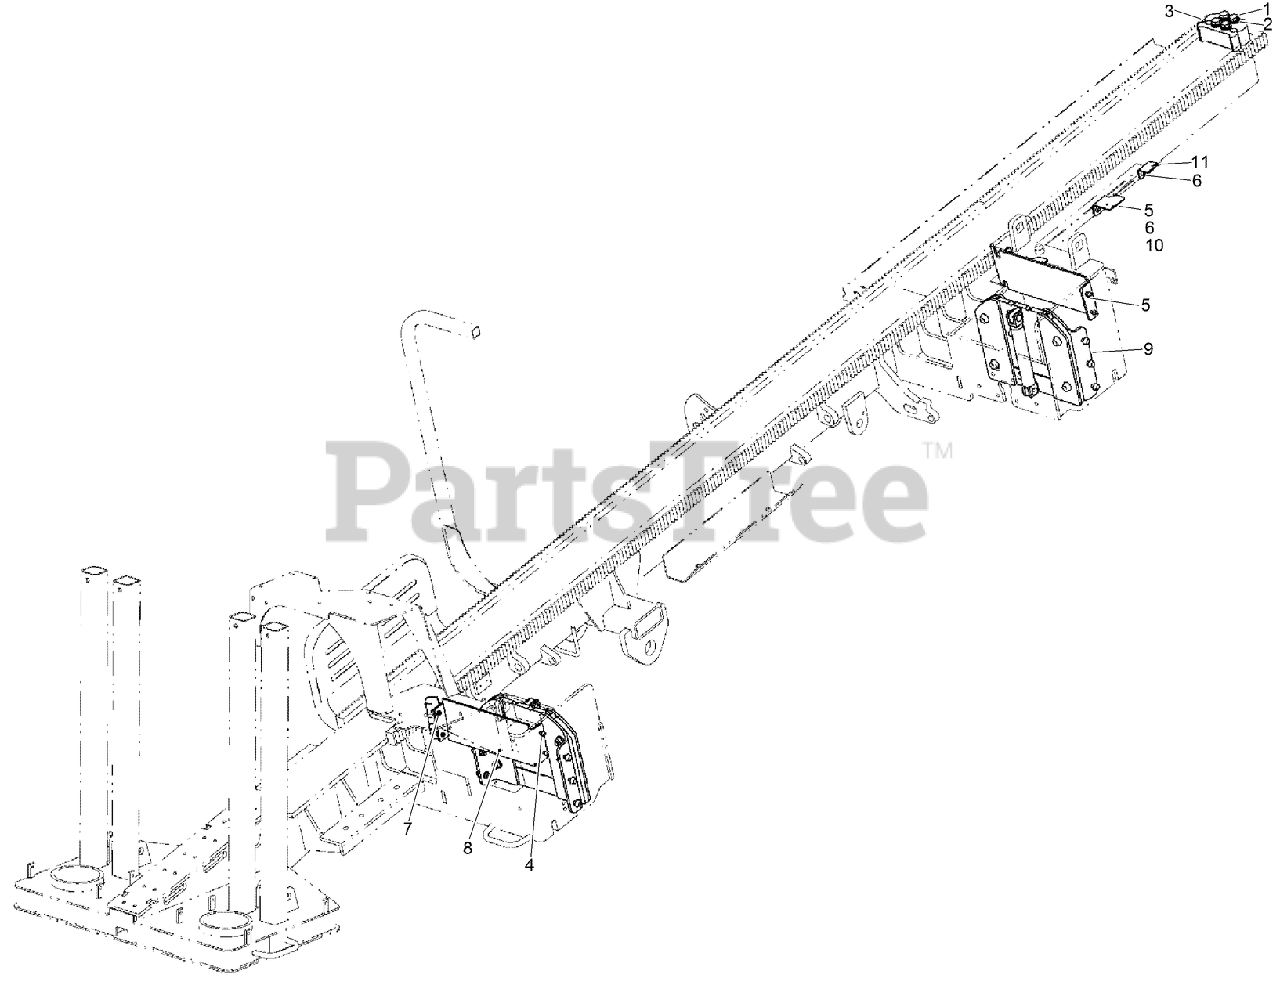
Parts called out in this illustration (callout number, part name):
1	SCREW-HH
3	STOP - Carriage
4	SCREW, METRIC FLANGE w/BODY - M8 x 35
5	NUT-TORQUE, PREVAILING
6	SCREW-HH
7	SCREW-HHF
8	ASSEMBLY - Deflector Plate
9	ASSEMBLY - Elevator
10	PLATE - Proximity Switch Mount
11	PLATE - Switch Mount
